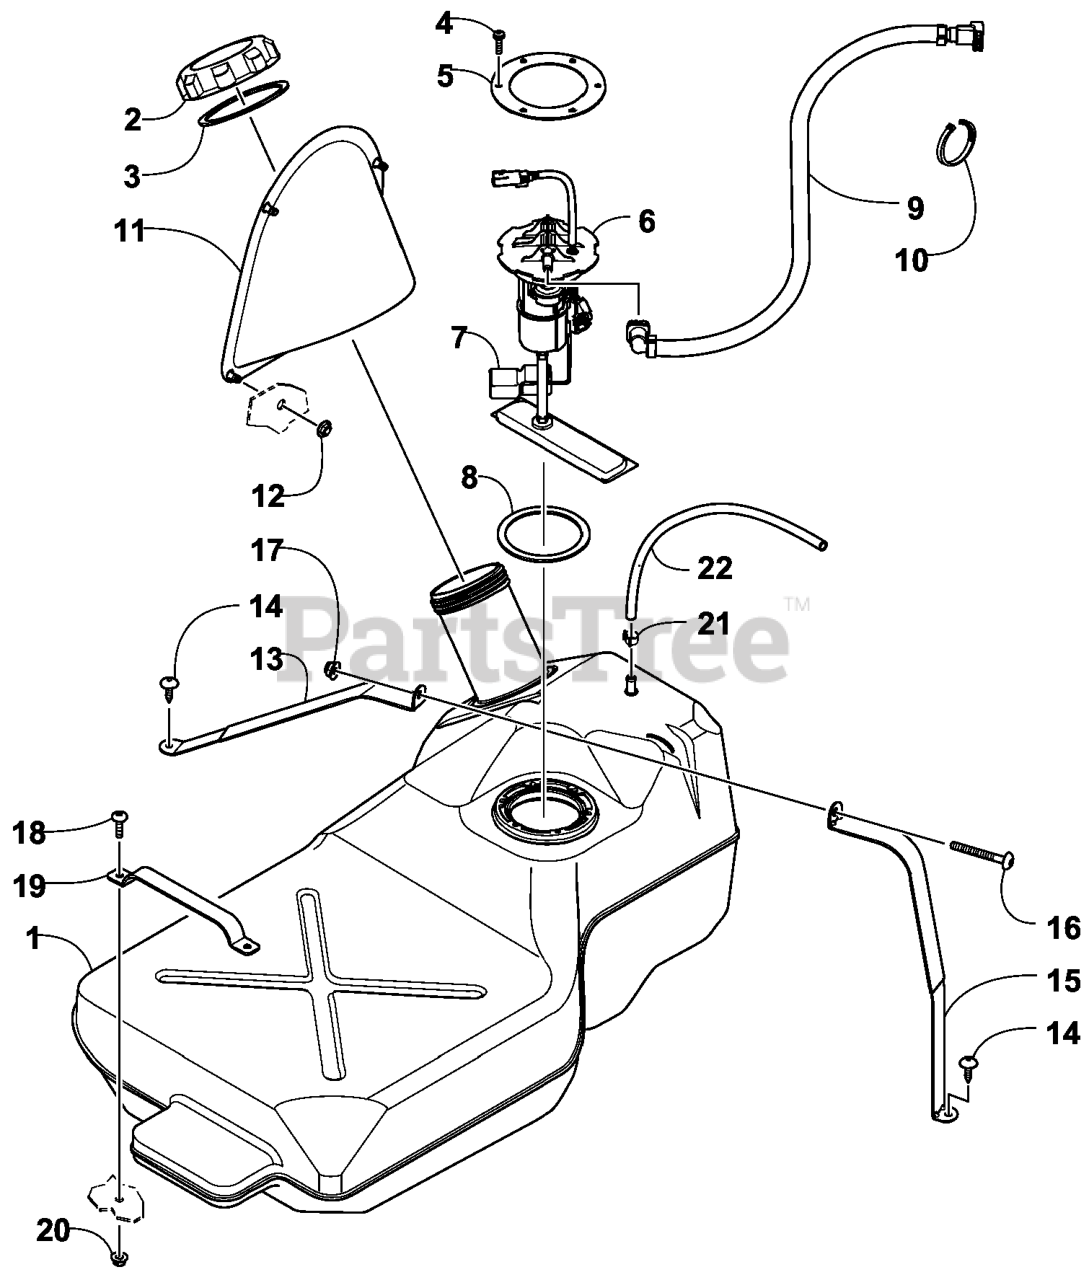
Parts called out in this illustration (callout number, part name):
1	FUEL TANK ASM
2	CAP-FUEL
3	SEALCAP, GAS
4	SCREW-TSPH, TF
5	MOUNT-PUMP, FUEL
7	FLOAT-FUEL PUMP
10	TIE-CABLE
11	INSERT-FUEL CAP
12	NUT-STAMPED
14	SCREW-TSTRH, SELFTAP
15	STRAP-FUEL TANK
16	JACKSHAFT
17	LINKAGE,LOWER CALIPER RH
18	SCREW-TSPRH
19	BRACKET-MOUNT, FUEL TANK
20	NUT-HH, SEMS
21	CLAMP-SNAP
22	HOSE-FUEL
